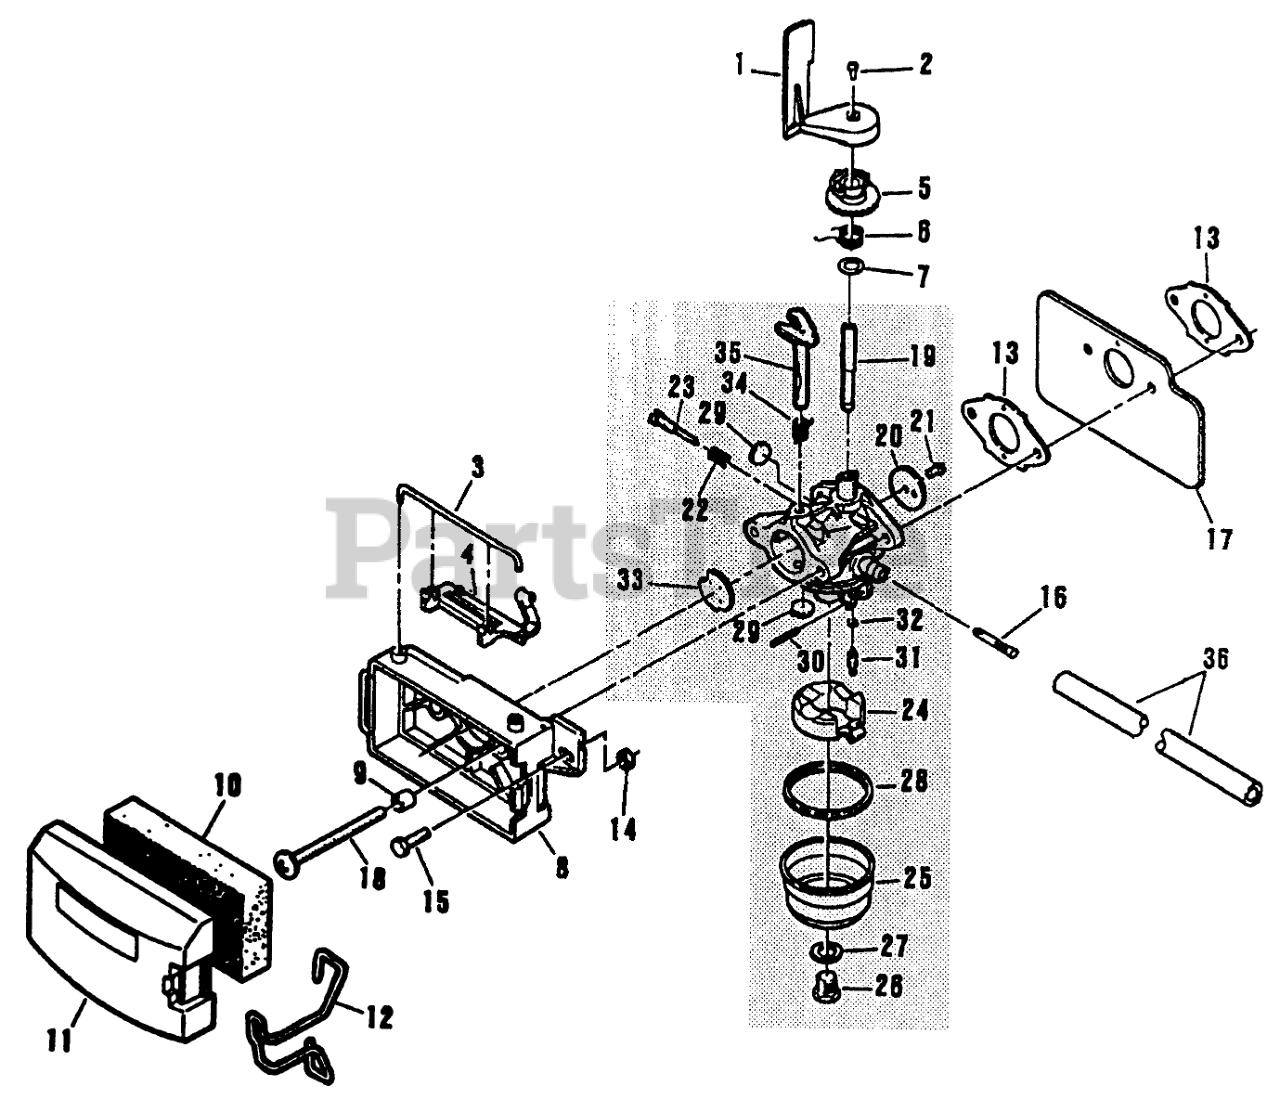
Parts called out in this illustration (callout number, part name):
1	AIR VANE F
2	SCREW F
3	RETAINER
4	LEVER F
5	COLLAR A/VAVE F
6	THROTTLE SPR E
7	WASHER VF
8	BASE,AIR FILT S
9	SPACER
10	ELEMENT-AIR FIL VF
11	Air Filter Cover
12	RETAINER-COVER, FILTER
13	GASKET CARB S
14	Nut
15	SCREW
16	SCREEN FUEL PITTS
17	Heat Shield
18	SCREW
19	Throttle Shaft
20	Throttle Plate
21	Screw-Throttle Plate
22	Spring-Idle Needle
23	Idle Needle
24	BOWL KIT S
25	Fuel Bowl
26	Screw-Bowl Retainer
27	Bowl Retainer Gasket
28	Fuel Bowl Gasket
29	Plug-Welch
30	Float Shaft
31	Inlet Needle Valve
32	Valve Seat
33	Choke Plate
34	Choke Return Spring
35	Choke Shaft
36	GAS LINE
